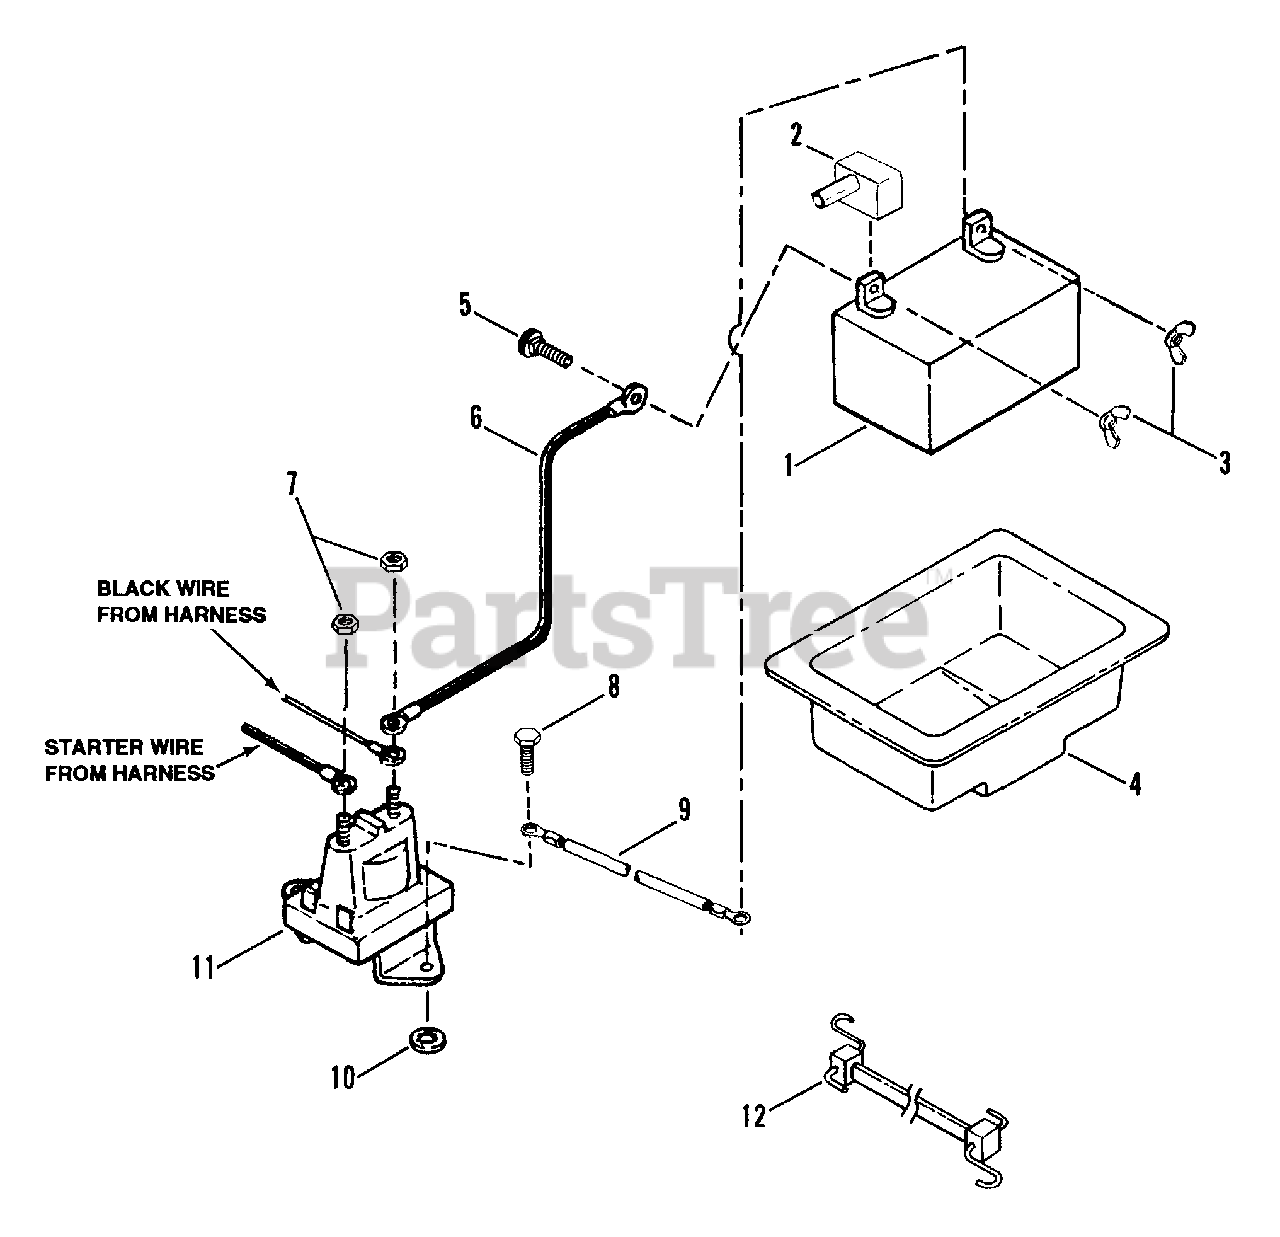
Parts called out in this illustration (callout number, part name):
1	KIT, Battery
2	COVER, Positive Terminal
3	WING-NUT, 1/4-20
4	TRAY, Battery
5	BOLT, 1/4-20 x 3/4" Carriage
6	CABLE, Positive (Red)
7	NUT, 1/4-20 Hex Jam
8	SCREW, 1/4-20 x 1/2" Self-Tapping
9	CABLE, Ground (Black)
10	RETAINER, 1/4 Bolt
11	SOLENOID
12	TIE, Strap
